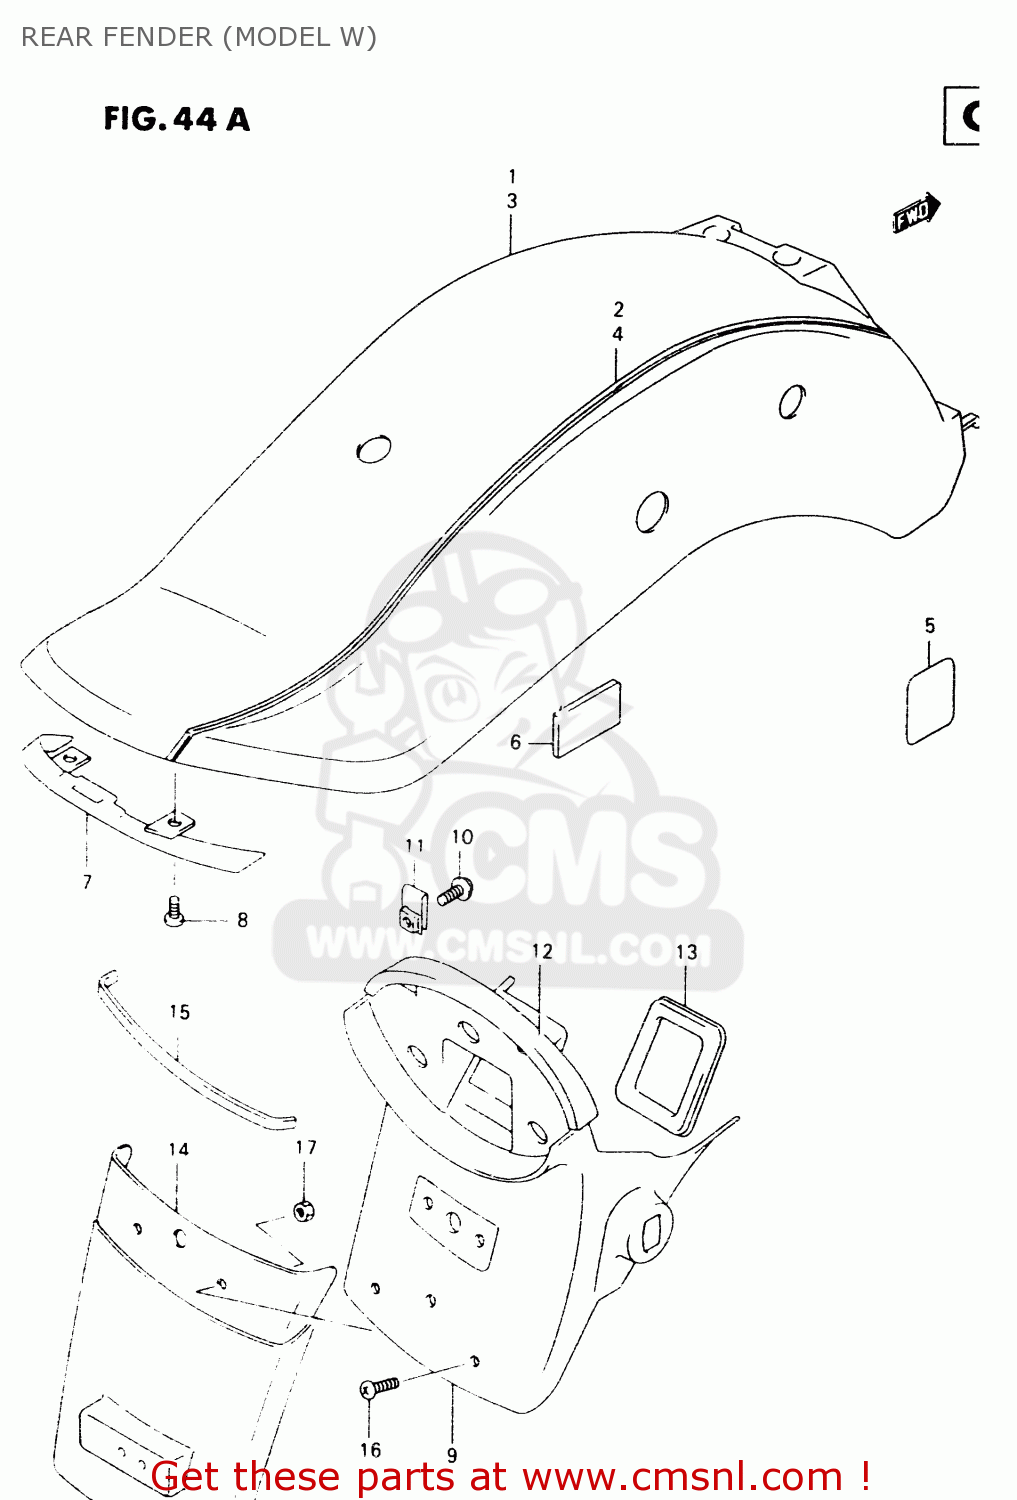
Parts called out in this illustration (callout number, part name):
1	FENDER,RR
2	TAPE SET,RR FENDER
3	FENDER,REAR
4	TAPE SET,RR FENDER
5	PAD
6	CUSHION
7	COVER,RR FENDER RR
8	SCREW
9	EXTENSION,RR FENDER
10	SCREW
11	PLATE,FRAME COVER
12	CUSHION,RR FENDER EXTENSION
13	CAP,RR FENDER EXTENSION
14	MUDGUARD,RR FENDER
15	CUSHION,RR FENDER EXTENSION
16	SCREW
17	NUT
